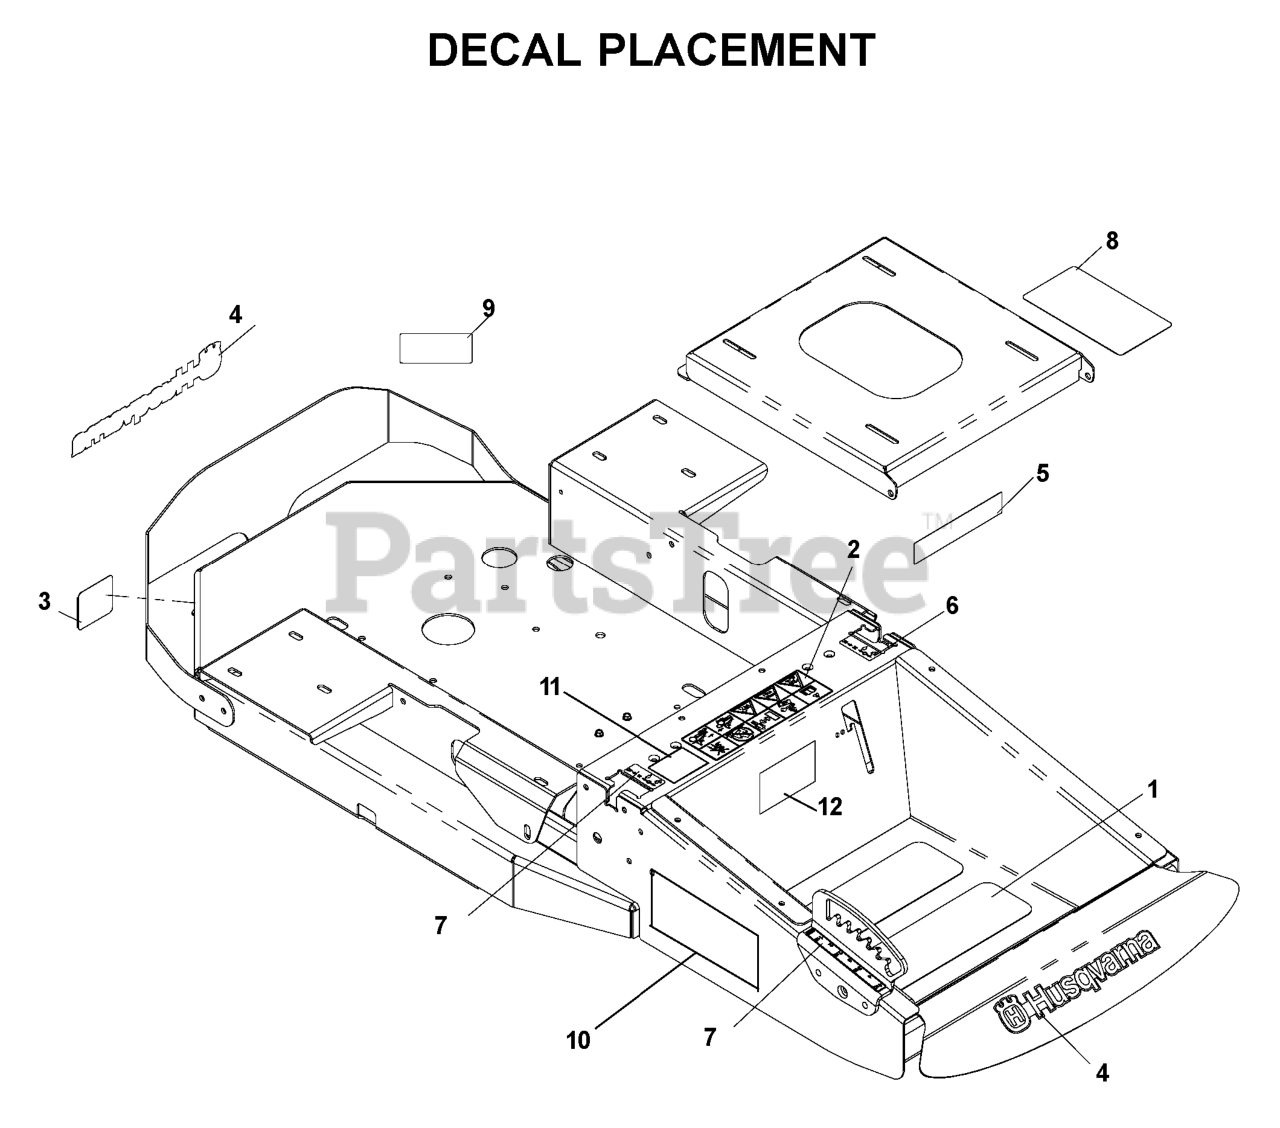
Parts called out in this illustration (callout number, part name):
1	ANTI-SKID PAD
2	DECAL, WARNING
3	DECAL, DO NOT TOW
4	DECAL, HUSQVARNA 12"
5	EURO DECAL-BATTERY WARNIN6
6	DECAL, MOTION CONTROL
7	DECAL, CUTTING HEIGHT
8	DECAL-SERVICE
9	DECAL, BELT DRIVE
10	DECAL, CZ4818
11	DECAL, EXITING MOWER
539109092	DECAL, CE DETAILS
